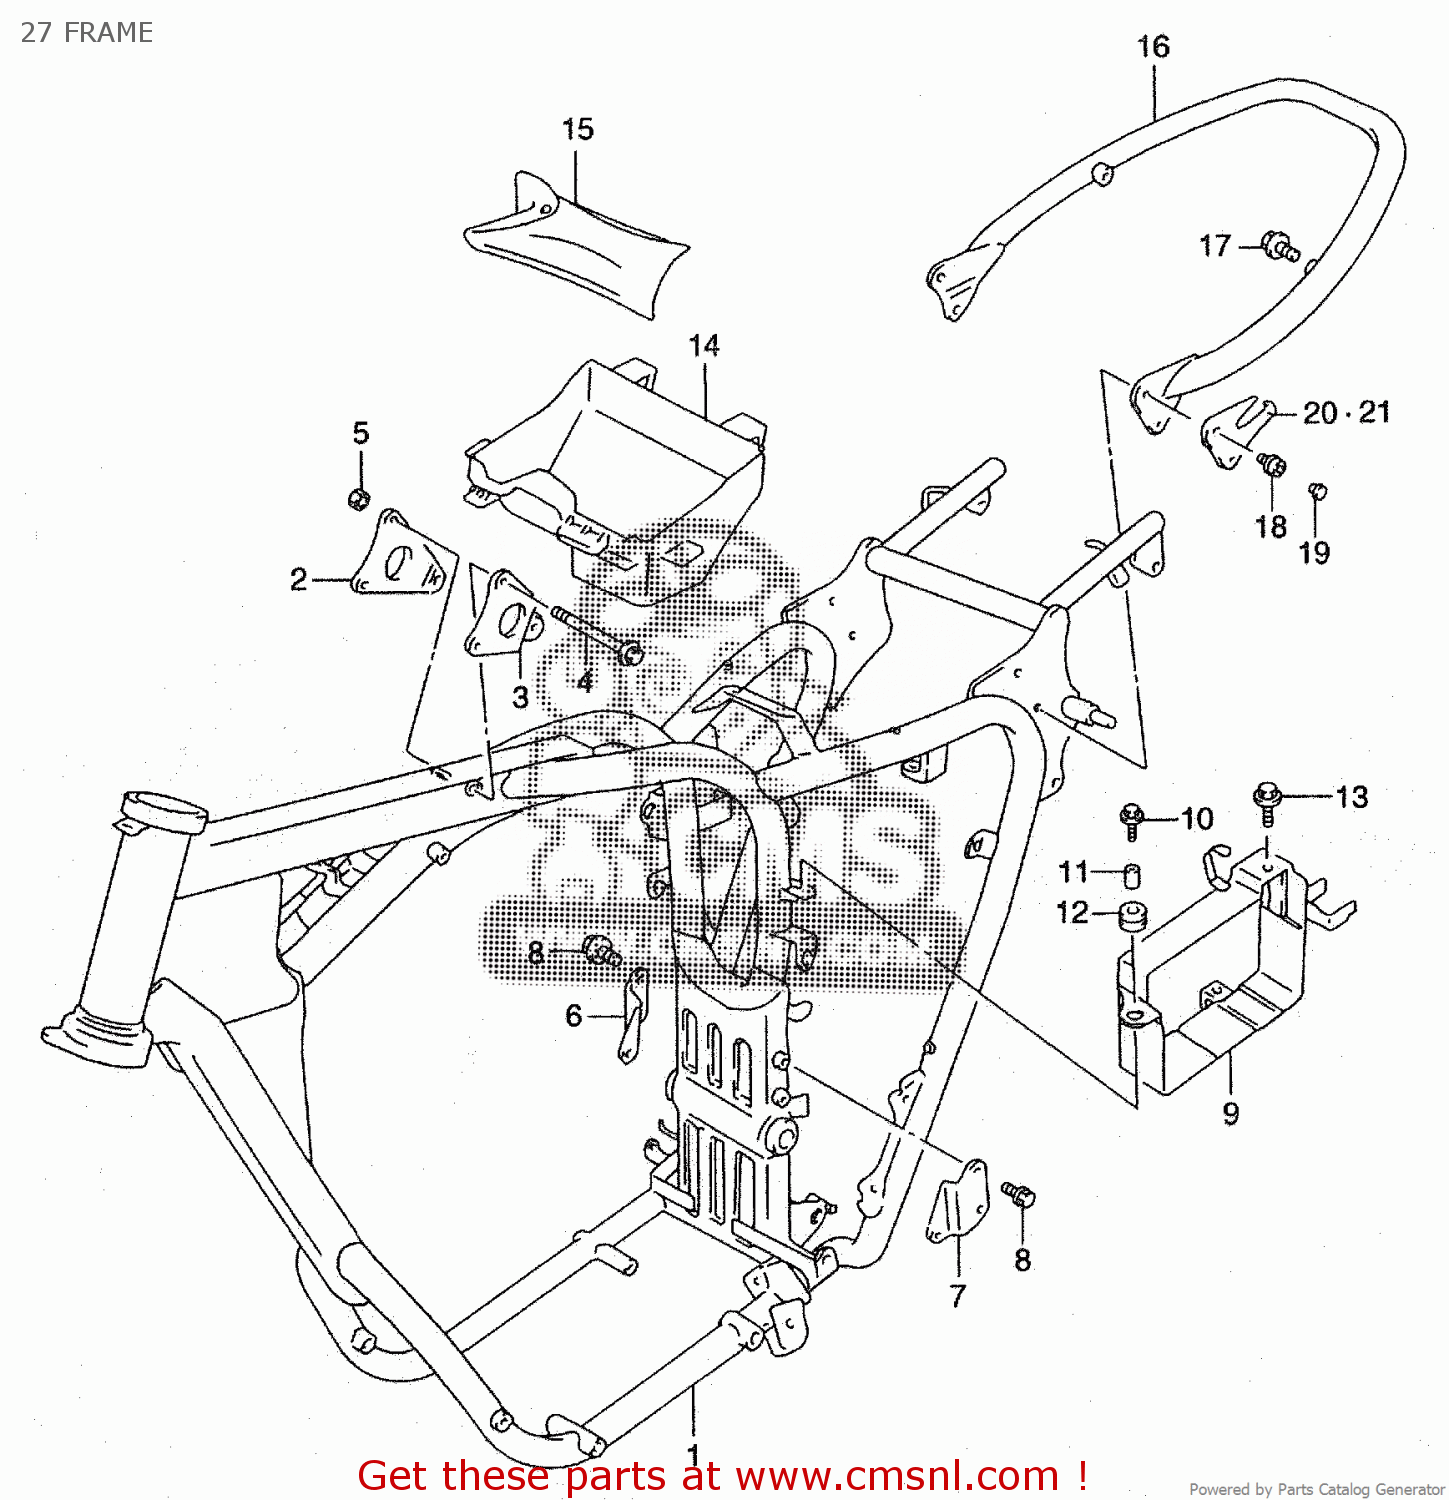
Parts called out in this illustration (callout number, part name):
4	BOLT(8X67)
5	NUT
8	BOLT
10	BOLT(6X16)
11	SPACER(6.5X9X8.5)
12	CUSHION
13	BOLT
15	TOOL ASSY
17	BOLT
18	BOLT
19	CAP(OD:11)
